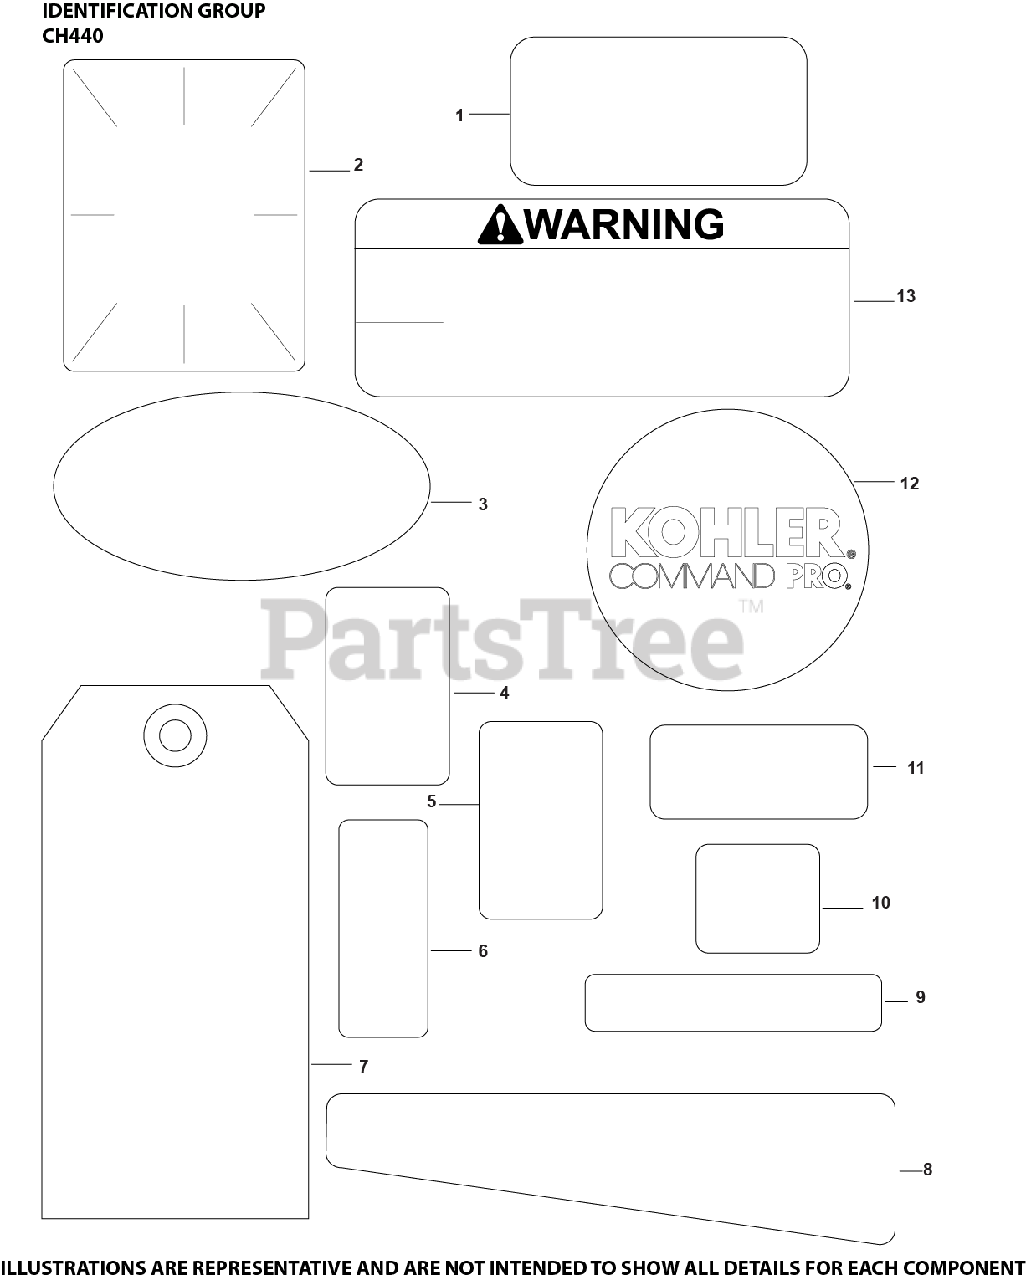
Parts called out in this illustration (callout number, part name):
1	LABEL, MAINTENANCE (CKY)
2	LABEL, CLEAR LAMINATION
7	TAG, HANG
